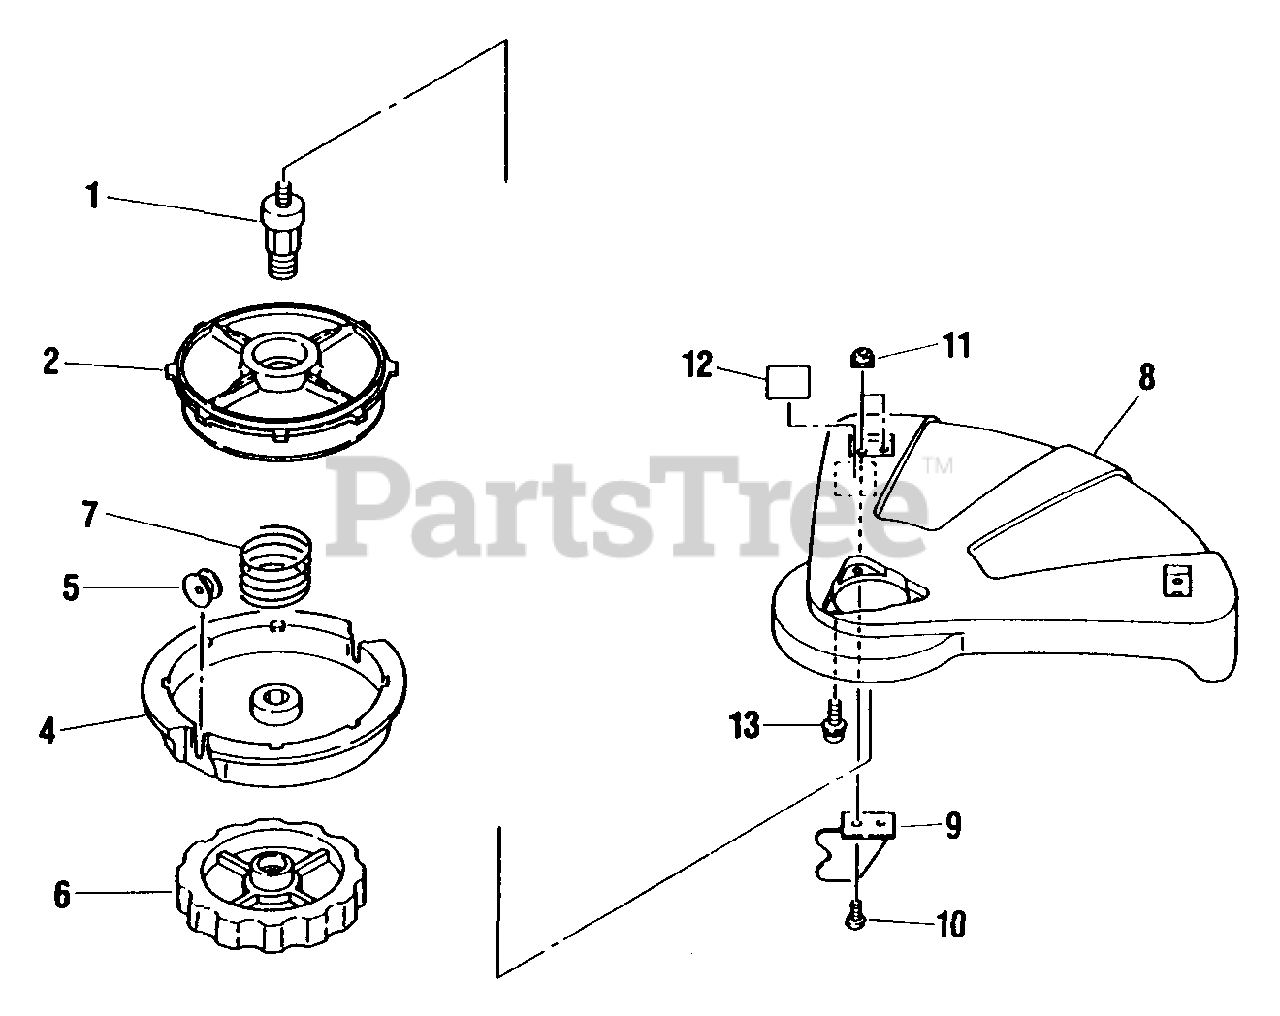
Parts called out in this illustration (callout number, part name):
1	SHAFT BOLT (8MM RH)
2	INNER SPOOL
4	SPOOL HOUSING
5	EYELET
6	KNOB
7	SPRING
8	GUARD
9	KNIFE, TRIMMER LINE
10	SCREW - 4X16
11	NUT - NYLON
12	LABEL - CAUTION
13	SCREW - 5X16
